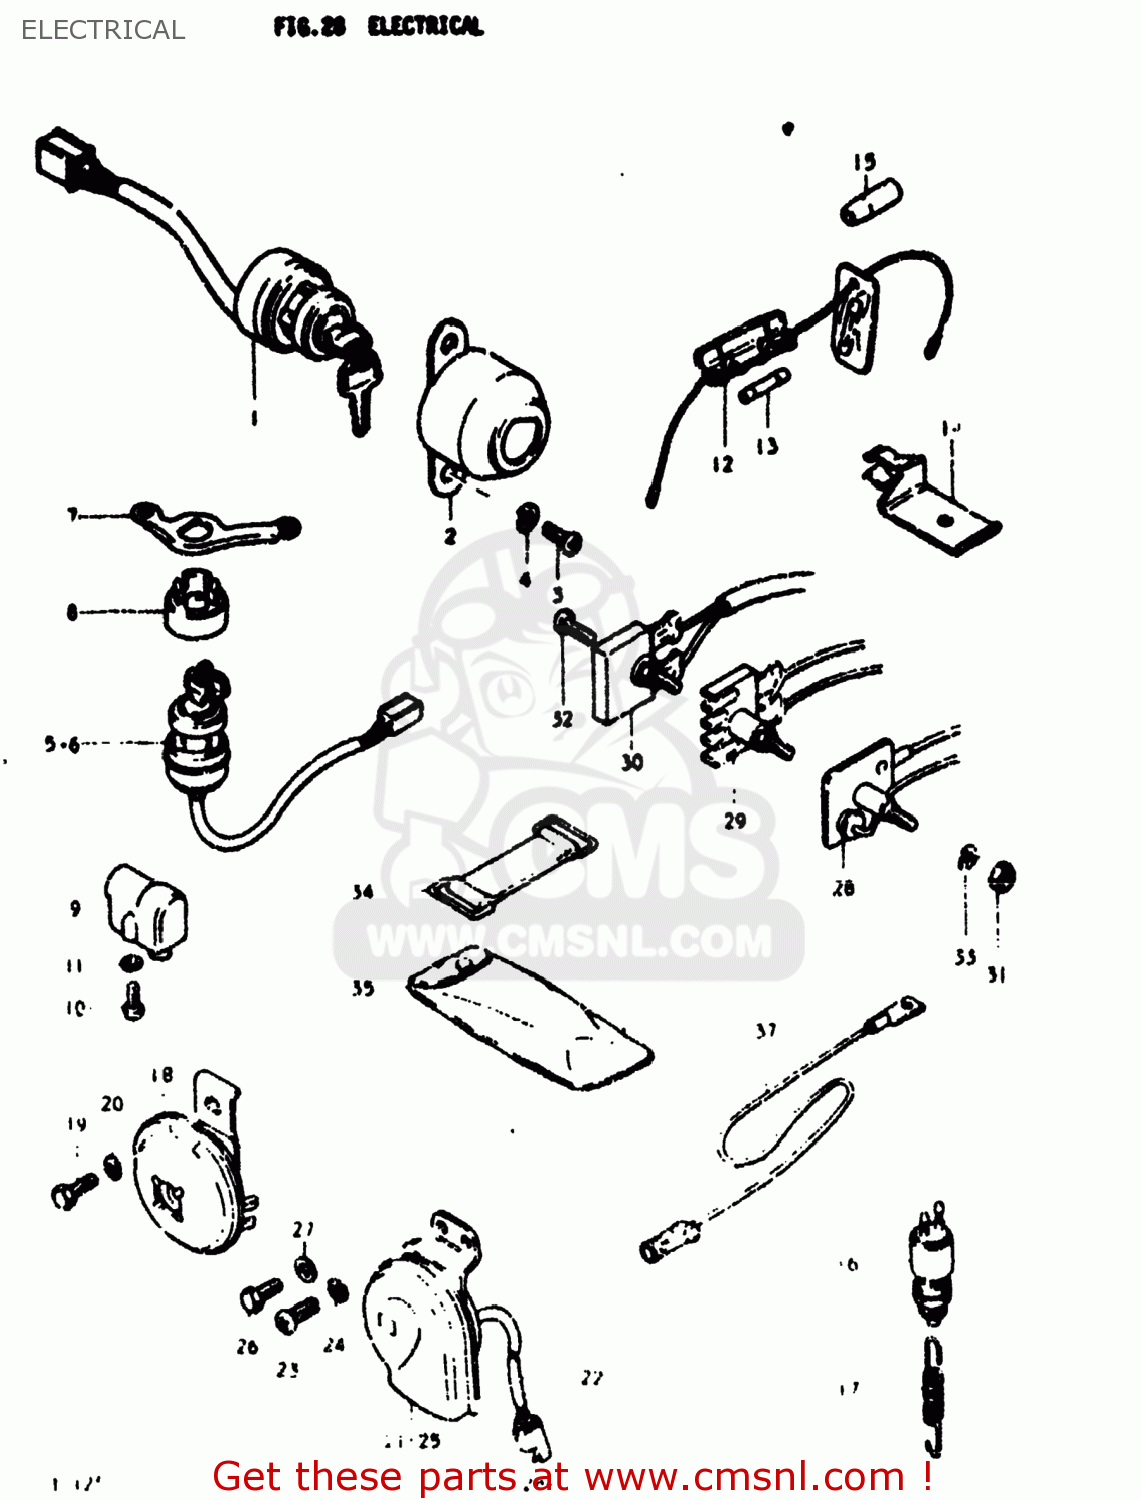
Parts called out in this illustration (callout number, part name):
1	SWITCH ASSEMBLY,IGNITION
2	BRACKET,IGNITION SWITCH
3	SCREW 6X12
4	LOCK WASHER
5	SWITCH ASSEMBLY,IGNITION
6	SWITCH ASSEMBLY,IGNITION
7	BRACKET,IGNITION SWITCH
8	IGN SWITCH COVE
9	LOCK ASSY,STEERING
10	Screw
11	LOCK WASHER
12	BOX ASSEMBLY,FUSE
13	FUSE(15A)
14	HOLDER,FUSE CASE
15	SEAL,DUST(10X17X45)
16	SWITCH ASSY,BRAKE LAMP
17	SPRING
18	HORN ASSEMBLY
19	BOLT
20	LOCK WASHER
21	HORN ASSEMBLY
22	WIRE
23	SCREW
24	LOCK WASHER
25	HORN ASSY
26	BOLT
27	WASHER
28	RECTIFIER ASSEMBLY
29	RECTIFIER ASSEMBLY
30	RECTIFIER ASSEMBLY
31	NUT
32	SCREW 5X20
33	LOCK WASHER
34	BAND
35	TOOL SET
36	WIRE,WIRING HARNESS LEAD
